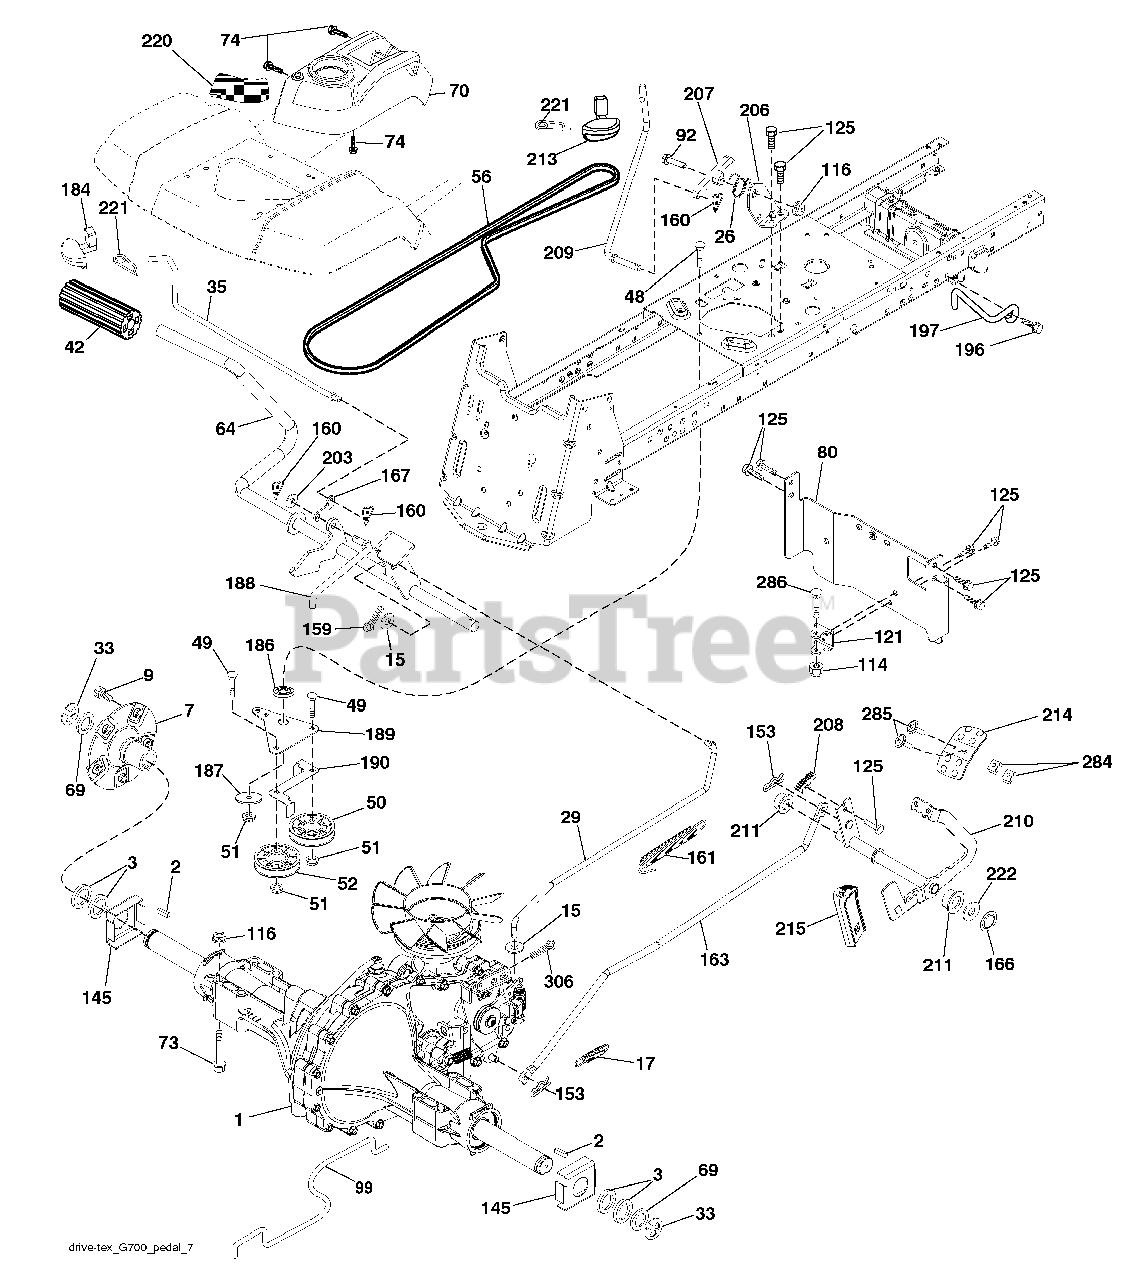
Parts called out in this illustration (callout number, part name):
2	Key 1/4 x 2.5
3	Washer Thrust Axle Hardened
7	Hub Asm. Wheel
9	Bolt Hub Wheel
15	Washer 13/32 x 13/16 x 16 Ga.
17	Spring, Brake
26	Spring Return Cruise
29	Rod, Brake
35	Rod, Brake, Park
42	Cover, Foot Pedal
48	Bolt Carr Sh 3/8-16 x 1-1/2 Gr.5
50	Pulley Idler Flat
51	Lock Nut 3/8-16
52	Idler V-Groove 910" Offset
56	V-Belt, Drive
64	Shaft Asm. Pedal Brake Control
69	Washer 1-1/32 x 1-5/8 x 16 Ga.
70	Console Asm
73	Bolt Hex 5/16-18 x 3 Gr. 5
74	Screw 1/4 x 1/2
80	Strap Torque
92	Bolt 5/16-18 x 1/2
99	Spring Bypass
114	Nut Lock Hex W/Ins. 5/16-18 unc
116	Nut Lock Hex Flange 5/16-18
121	Bracket Strap Torque
125	Screw 5/16-18 x 3/4
145	Washer Axle Flange
153	Retainer Spring
159	Pin Cotter 1/8 x 3/4
160	Retainer Clip
161	Spring, Return, Clutch
163	Rod Pedal Control
166	Nut Push .625
167	Latch Brake Parking
184	Handle Parking Brake
186	Spacer Retainer
187	Washer
188	Link Clutch Ground Drive
189	Bellcrank Ground Drive
190	Keeper Bellcrank Ground Drive
196	Screw 3/8-16 x 1
197	Bracket Clutch Anti-Rotation
203	Washer 11/32 x 11/16 x 16 Ga.
206	Bracket Mount Latch Cruise
207	Latch Control Cruise
208	Gear Sector Control Cruise
209	Rod Control Cruise
210	Rocker Asm. Pedal Control
211	Bearing Nylon
213	Knob Control Cruise
214	Pedal Forward
215	Pedal Reverse
220	Reflector RH
221	Retainer Spring Clip Handle
222	Washer 21/32 x 1-1/4 x 10 Ga.
284	Nut U channel 1/4-20
285	Screw PHD 1/4-20 Box Drive
286	Bolt 5/16-18 x 2.50
306	Pin Cotter 1/8 x 1
